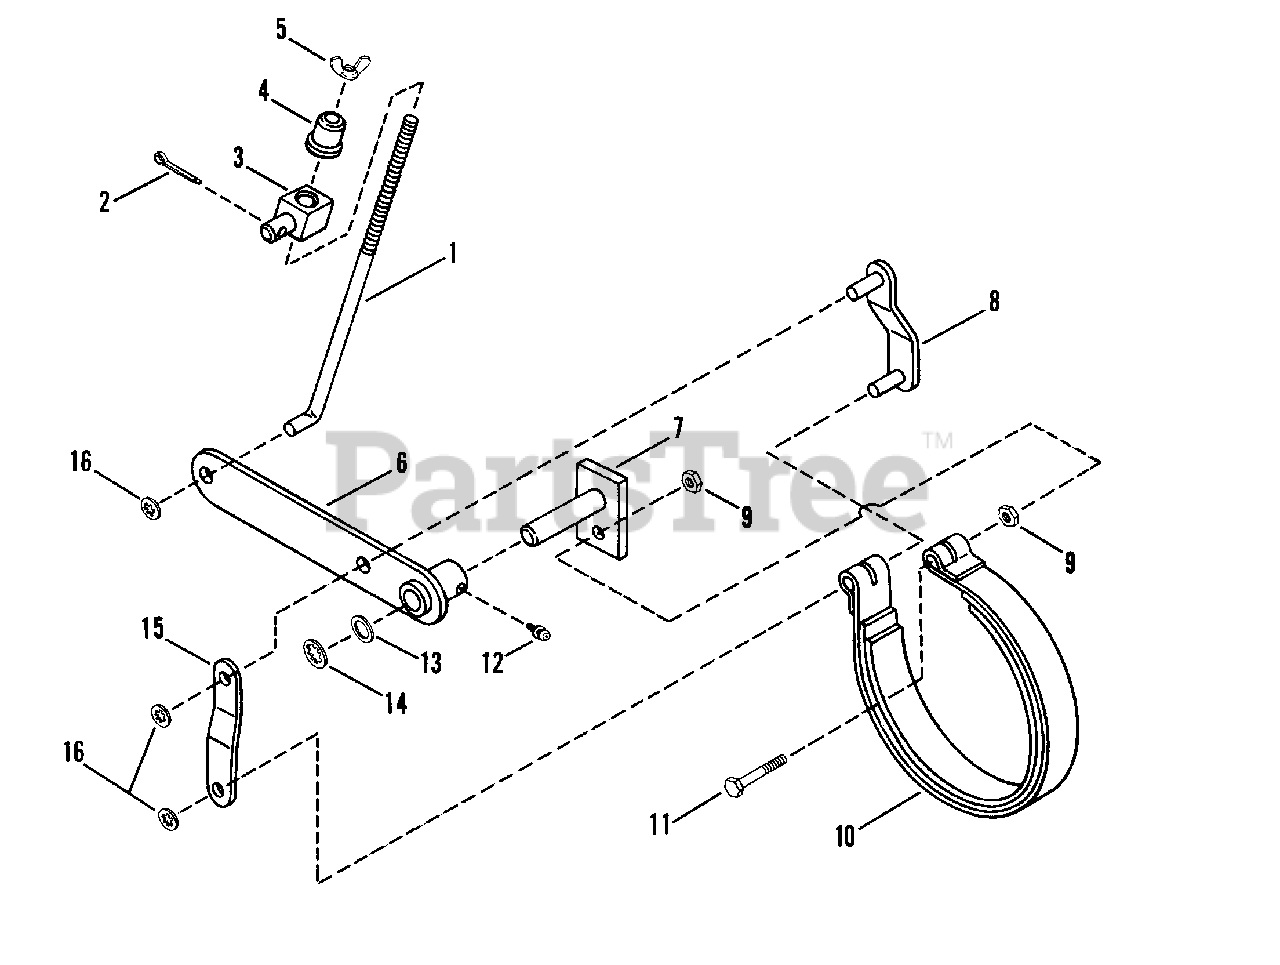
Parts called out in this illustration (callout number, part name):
1	ROD, Brake
2	COTTER-PIN, 3/32 x 1"
3	SWIVEL, Brake Link
4	BUSHING
5	WING-NUT, 3/8-16 Nyloc
6	LEVER, Brake
7	BRAKE MOUNT STUD, Weldment
8	LINK, Brake
9	NUT, 3/8-16 Hex
10	BAND, Brake, 6"
11	BOLT, 3/8-16 X 2, GD5, CZ
12	FITTING, Lube
13	BUSHING, Machinery, 5/8" I.D., 1" O.D.
14	RETAINER, 5/8"
15	PLATE, Brake Link
16	RETAINER, 3/8"
